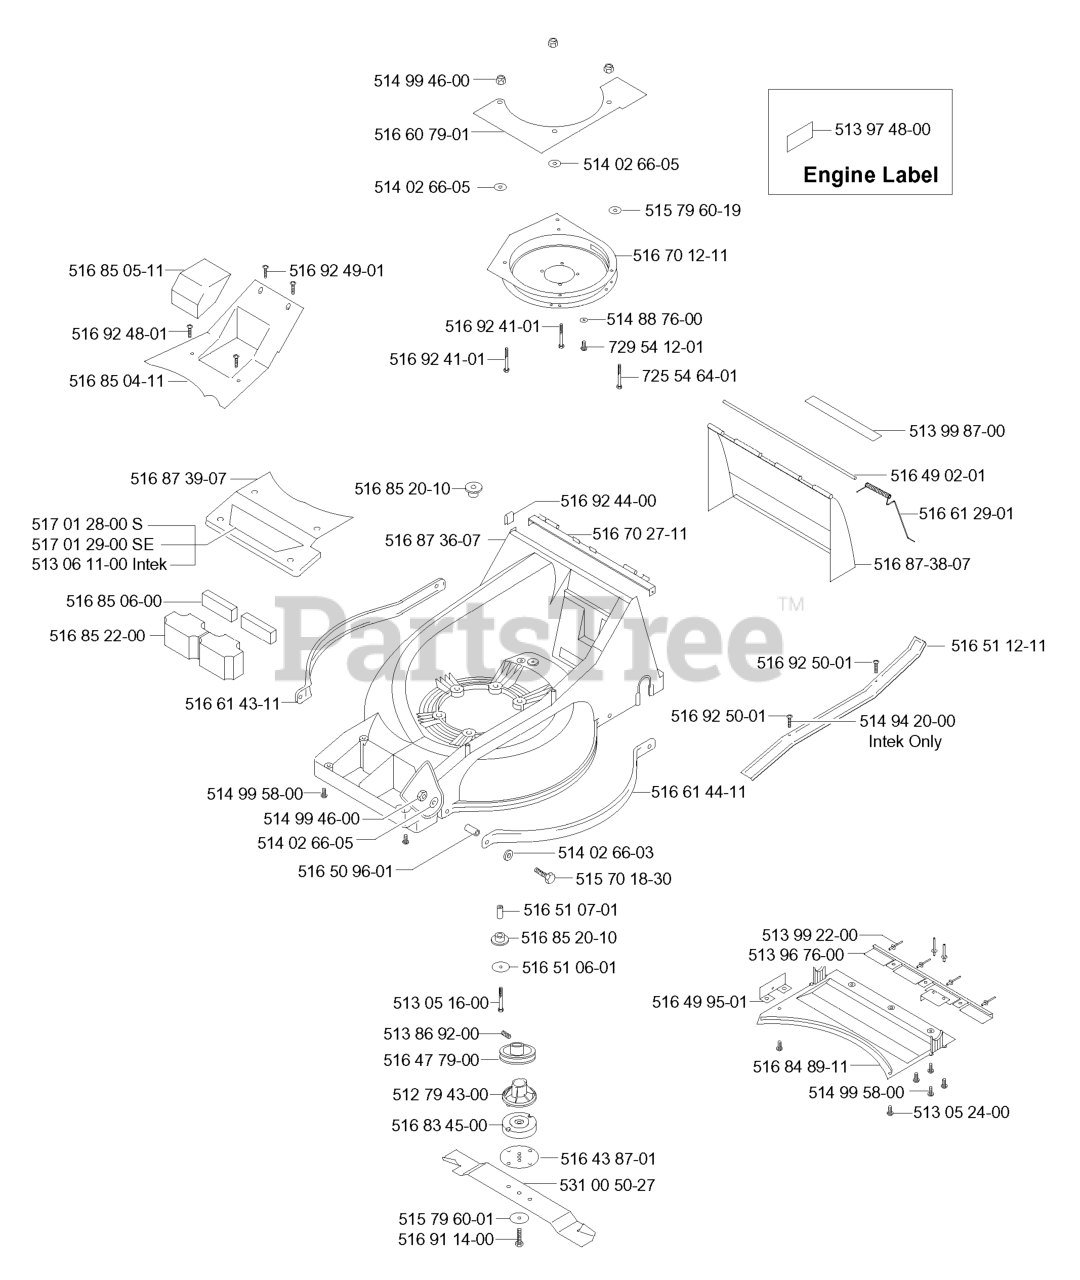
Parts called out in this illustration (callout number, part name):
6	LOCKNUT M8
8	SPACER
9	SCREW IHCSFM
9	BOLT REAR WHEEL
12	PULLEY ASSY
14	SCREW
15	LOCKNUT M8
17	%PULLEY
18	BALL BEARING 6004-2RS1
19	RETAINING RING
24	WASHER
26	LOCKNUT M8
28	BOLT FLANGE - M6X20
29	LOCKNUT M6
35	WASHER
